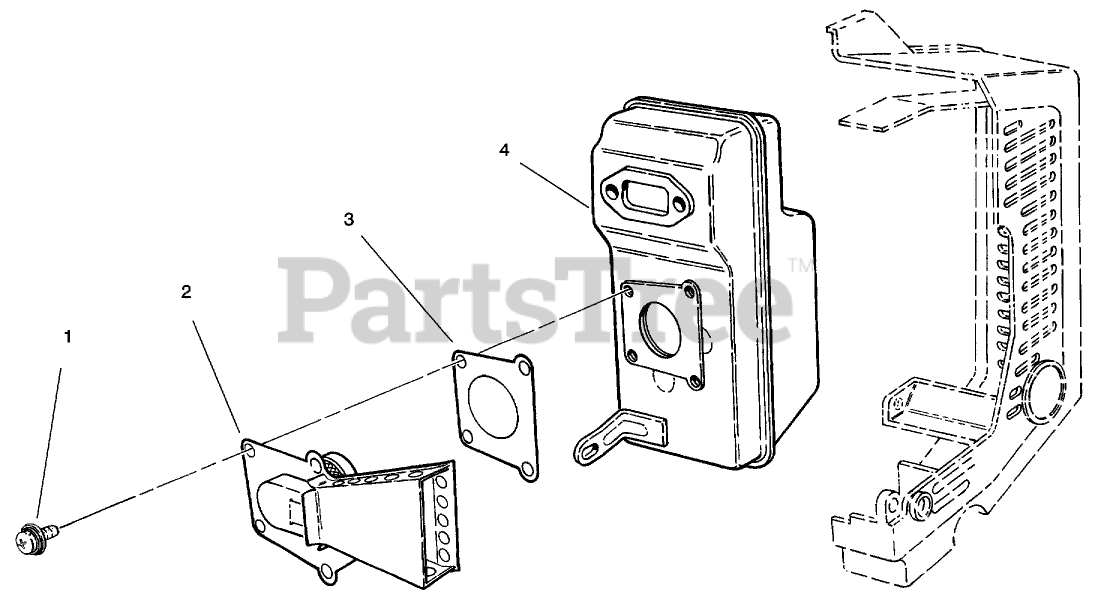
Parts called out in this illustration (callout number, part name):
1	Screw/Washer
2	Spark Arrester
3	GASKET
4	Muffler
